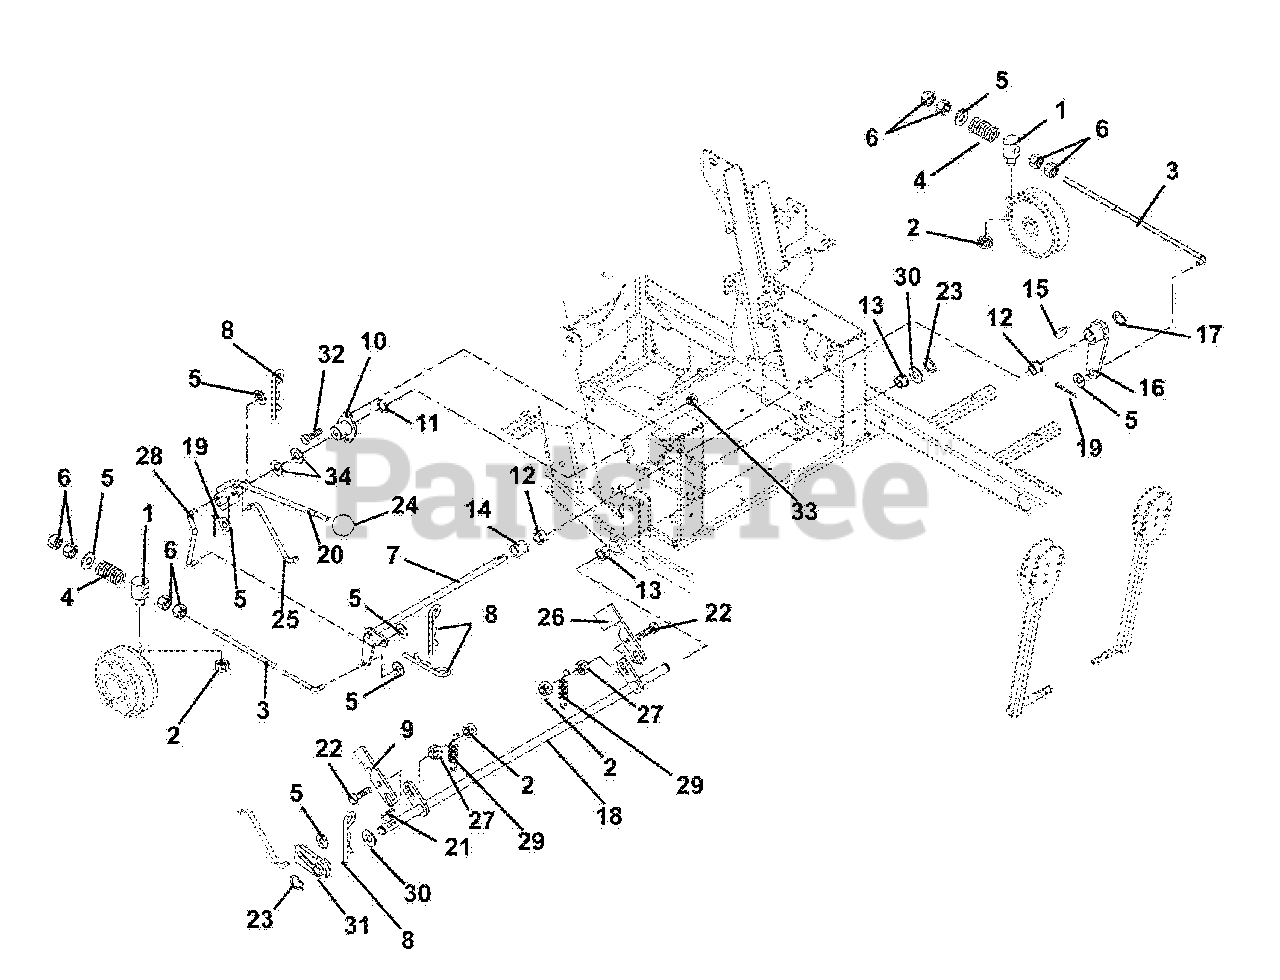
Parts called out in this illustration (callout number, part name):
1	Pivot, Brake Rod
2	Nut, Locking Center .31-18
3	PTO Link Rod
4	Spring, Compression .142 x .710 x 1.75
5	Washer, Flat Steel .406 x .812 x .065
6	Nut, Hex .38-16
7	Shaft, Brake Cross
8	Pin, Hair
9	Slide, Interlocking Brake
10	Bushing, Flange
11	Ring, Retaining External .625 x .05
12	Bushing, Flange Nylon .762 x 1.00 x .58 x 1.48
13	Bushing, Flange .515 x .75 x .745 x 1.00
14	Bushing, Sleeve .75 x 1.00 x .75
15	Key, Woodruff .19 x .75 Hard #9
16	Arm, Brake
17	Ring, Retaining External .69 x .077
18	Weldment, Mechanical Brake
19	Pin, Cotter External .09 x .75
20	Weldment, Brake Actuating
21	Key, Woodruff .13 x .63
22	Bolt, Round Head Square Neck .31-18 x 1.25 Grade 5
23	Ring, Retaining External .50 x .05
24	Knob, Steering Lock
25	Linkage, Brake Actuating
26	Interlock, Safety Switch
27	Nut, Locking Top Flange .31-18
28	Linkage, Brake Actuating
29	Spring, Tension .048 x .44 x 1.75
30	Washer, Flat Steel .505 x 1.00 x .062
31	Weldment, Parking Brake Hub
32	Bolt, Hex .31-18 x .75 Grade 5
33	Nut, Locking Top Flange .31-18
34	Washer, Flat Steel .630 x 1.25 x .062
